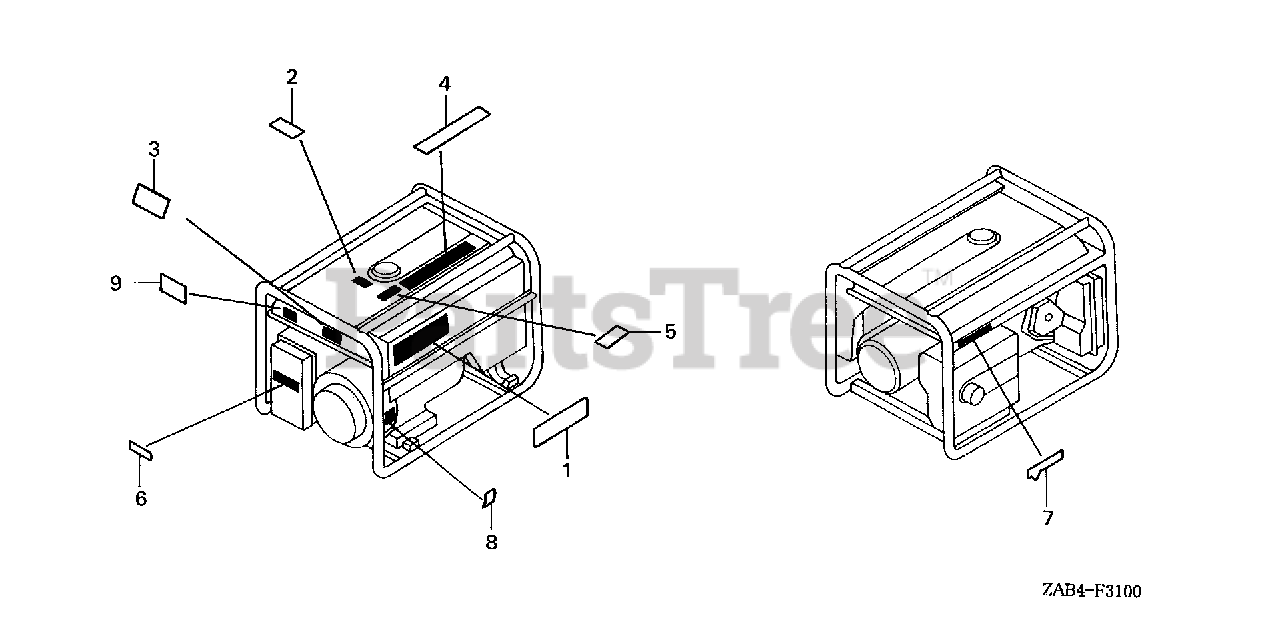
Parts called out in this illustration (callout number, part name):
1	MARK, EMBLEM (EM6000GP)
2	LABEL, FUEL CAUTION
3	PLATE, CAUTION
4	LABEL, OPERATOR WARNING (E)
5	MARK, CAUTION
6	MARK, AIR CLEANER
7	MARK, EX. CAUTION (ENGLISH/FRENCH)
8	MARK, OIL CAUTION
9	LABEL, PRESSURE CAUTION
